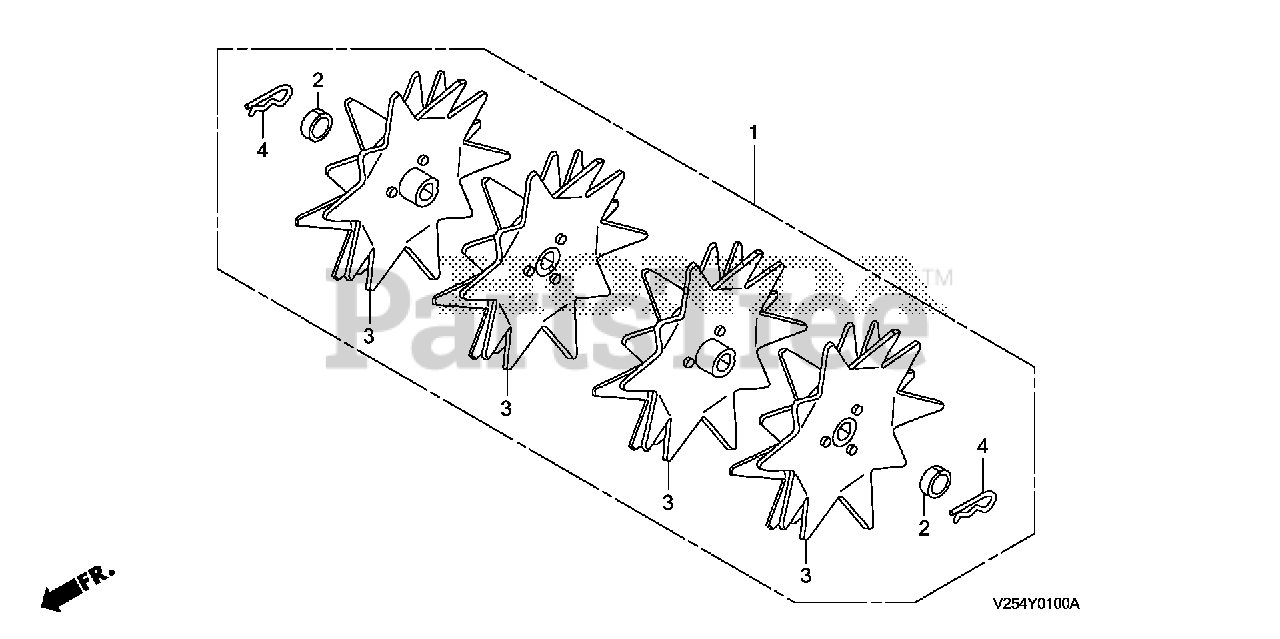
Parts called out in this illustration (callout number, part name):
1	TINES KIT, DIGGING
2	SPACER (17X9) (NOT AVAILABLE)
3	TINE, DIGGING
4	PIN, LOCK (17MM)
